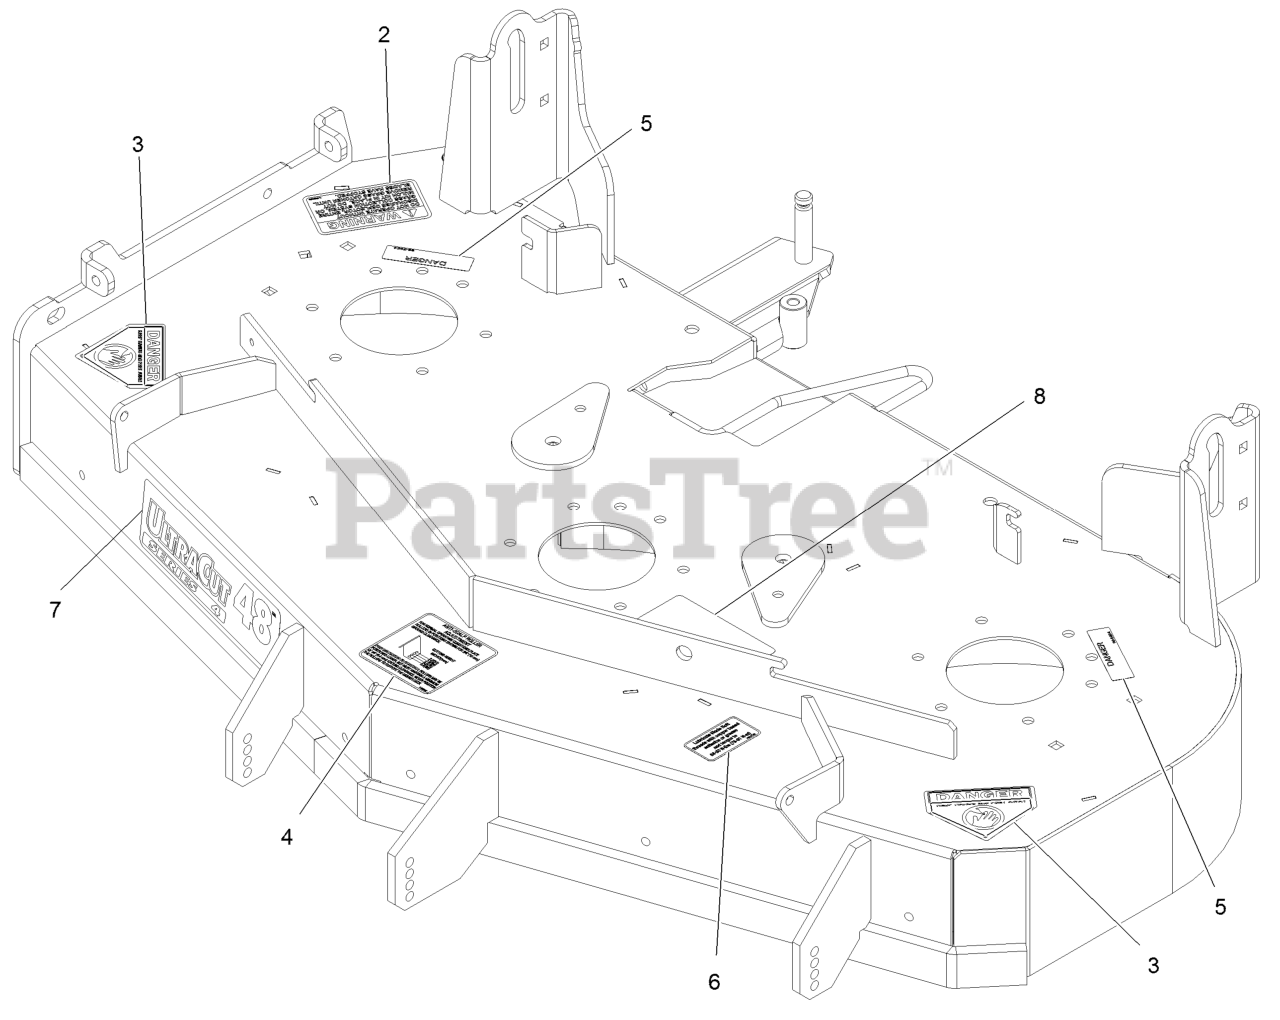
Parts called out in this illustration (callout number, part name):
2	DECAL-WARNING, DISCHARGE
3	DECAL-DANGER
4	DECAL,ANTISCALP
5	DECAL-COVER, MISSING
6	DECAL,BOLT TORQUE
7	DECAL,ULTRACUT 48 SERIES
8	DECAL,BELT ROUTING
